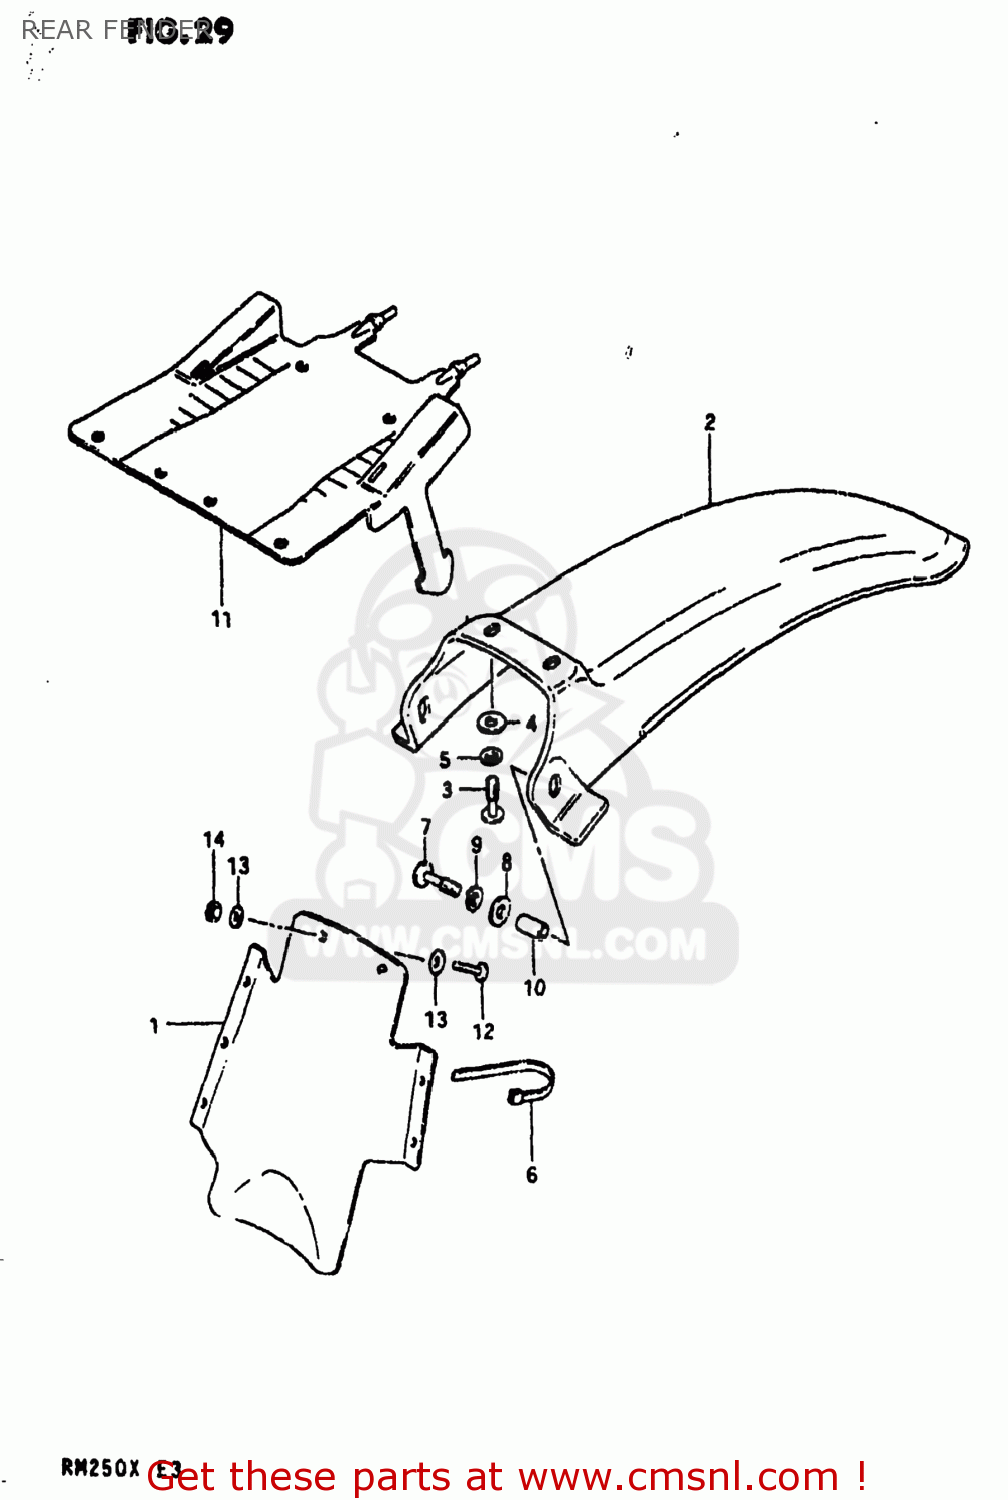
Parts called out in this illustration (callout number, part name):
1	FENDER,REAR
2	FENDER,REAR
3	SCREW
4	WASHER (6.5X20X1.2)
5	LOCK WASHER
6	CLAMP
7	SCREW
8	WASHER (6.5X20X1.2)
9	LOCK WASHER
10	SPACER
11	GUIDE,RR FENDER MUD
12	SCREW
13	WASHER
14	NUT
